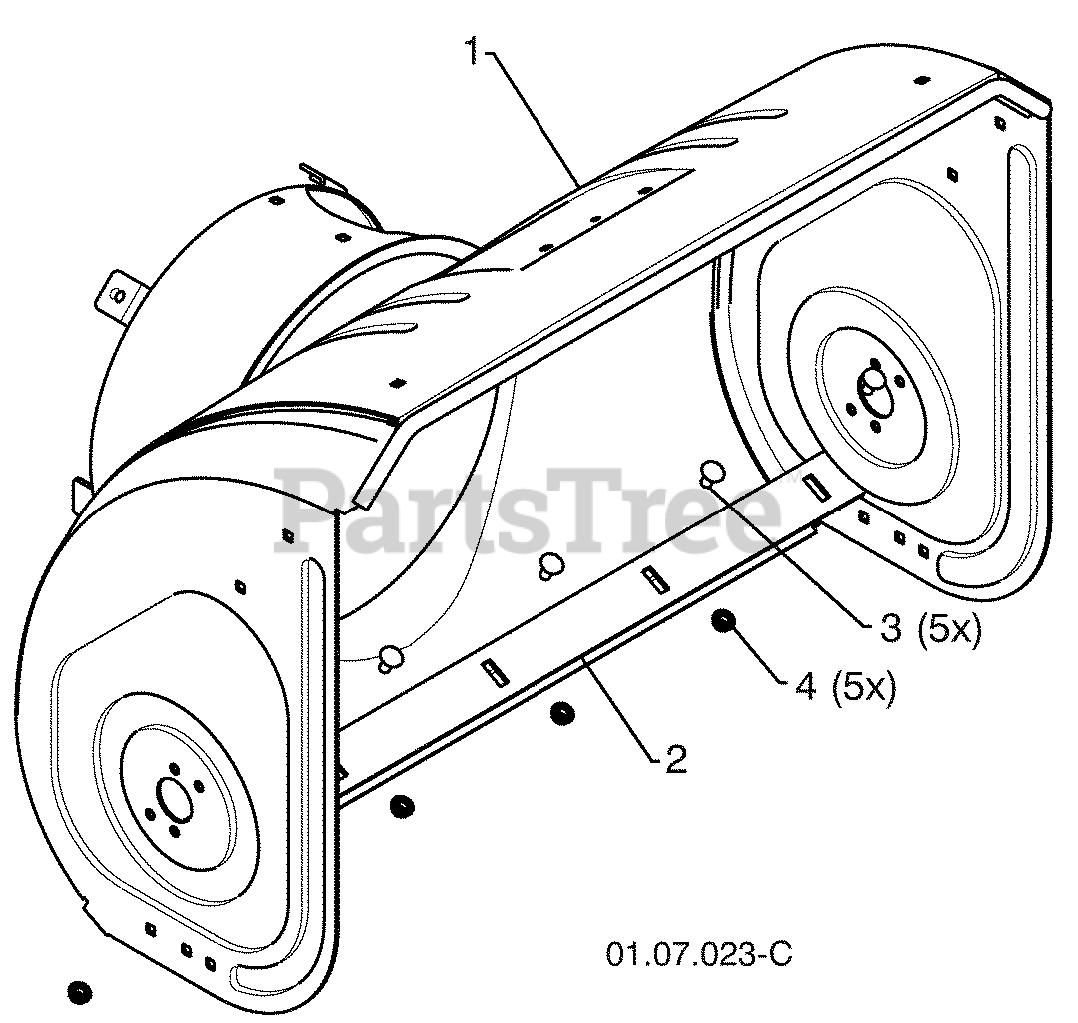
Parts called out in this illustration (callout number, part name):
1	HOUSING.AUG.WELDMENT.30.ORANGE
2	RP BAR.SCRAPER.30.BLACK
3	BOLT
4	NUT.FLANGE.5/16
